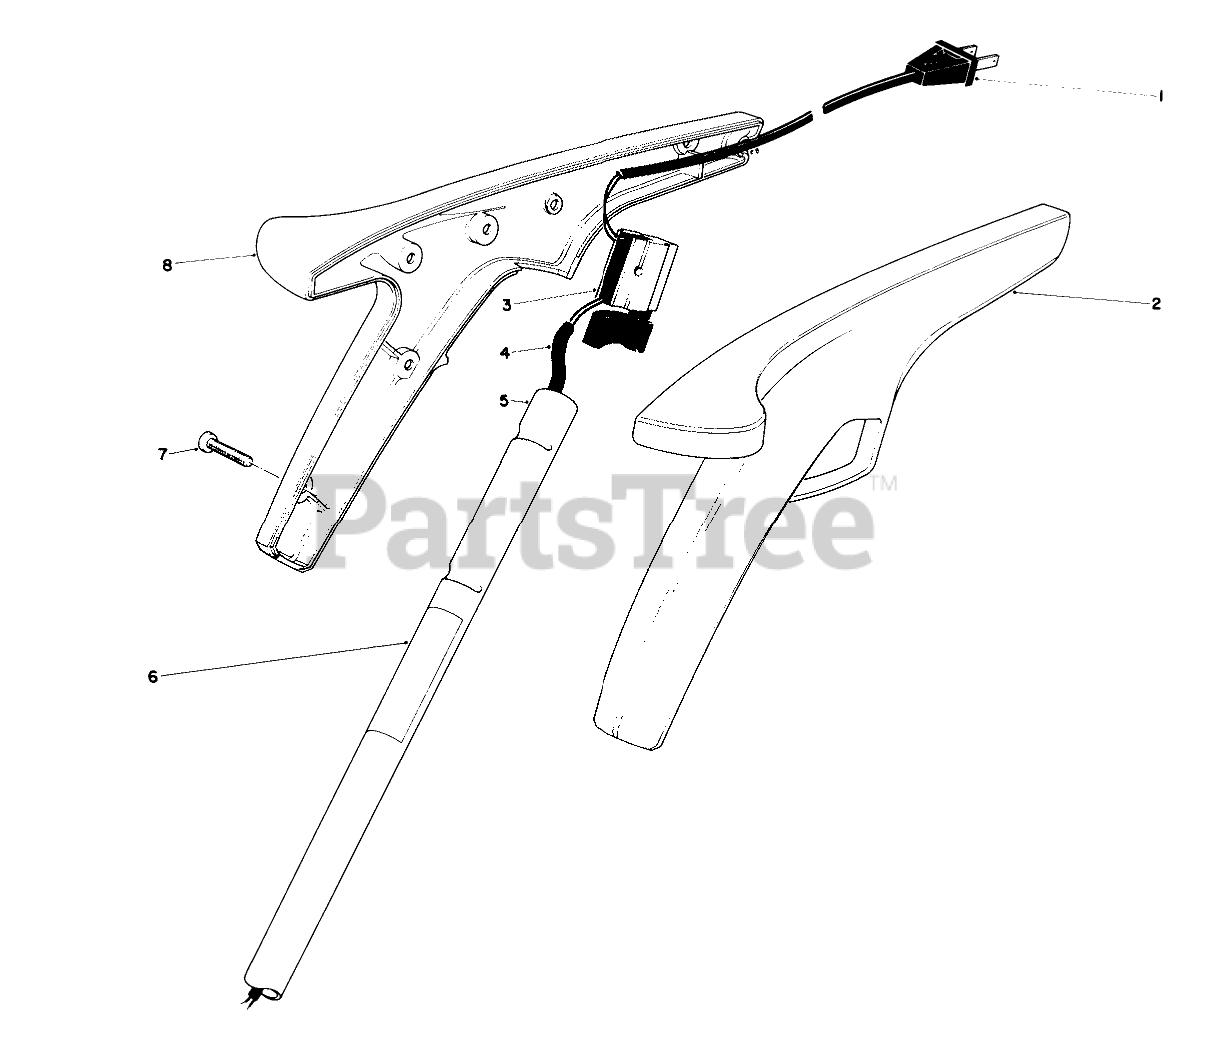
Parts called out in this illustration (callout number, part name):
1	Plug-Pigtail
2	LH HANDLE GRIP
3	SWITCH SINGLE SPEED
4	Wiring Harness
6	Decal-Serial Number
7	Screw
8	Grip-Right Hand
